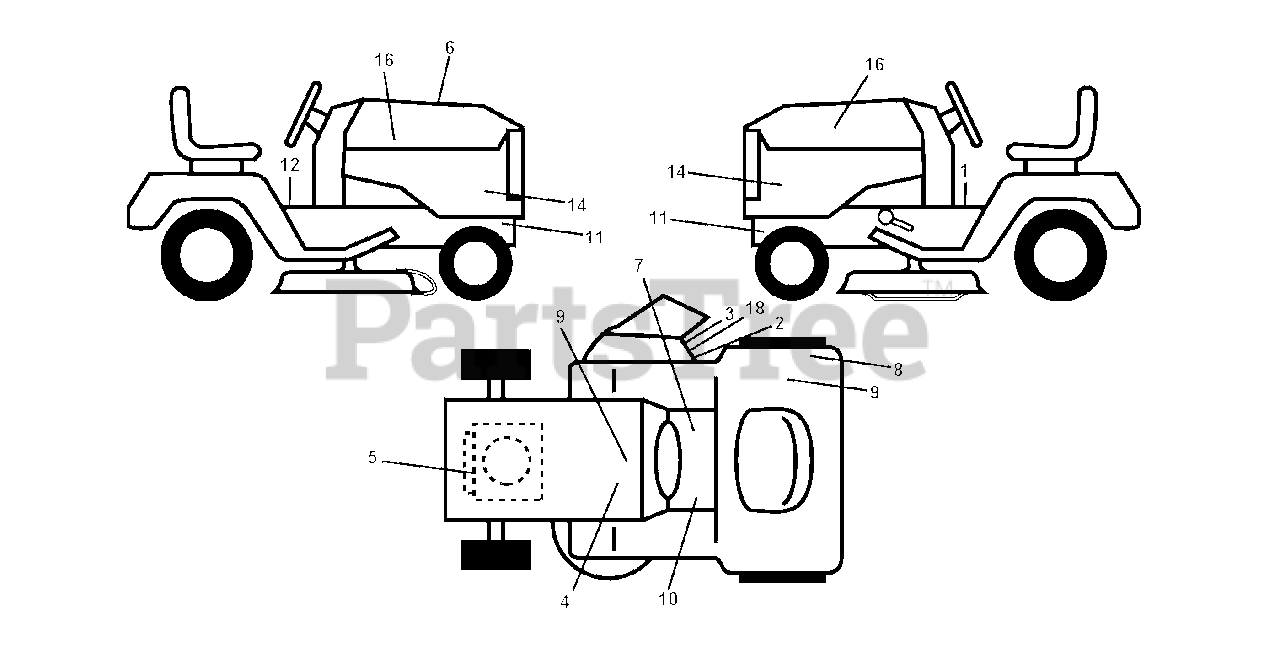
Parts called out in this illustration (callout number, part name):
1	DECAL
2	DECAL.MOWER.SCH.48/54
3	DECAL.INTERNATIONL.CUTFINGER
4	DECAL BTRY SYMBOLS
5	DECAL
7	LABEL
8	DECAL
9	DECAL 80 DBA
10	DECAL
12	DECAL PARK BRAKE
16	RP.DECAL.BADGE.170MM.TEXTLOGO
18	DECAL, DEFLECT WARNING
